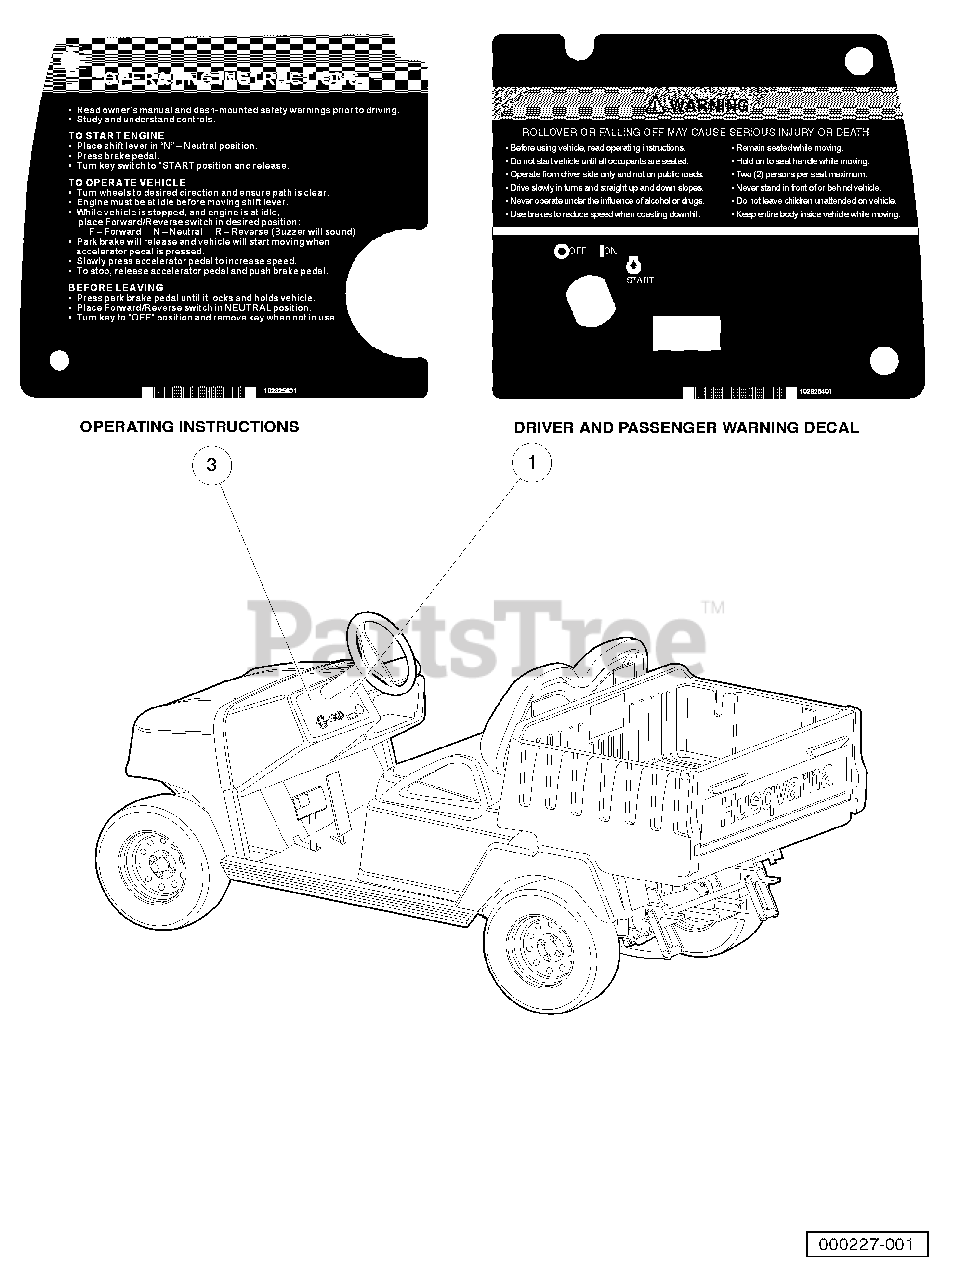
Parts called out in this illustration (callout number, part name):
1	Decal, Warning, Instrument Panel
2	Decal, Warning, Instrument Panel
3	Decal, Operating Instructions, Instrument Panel
